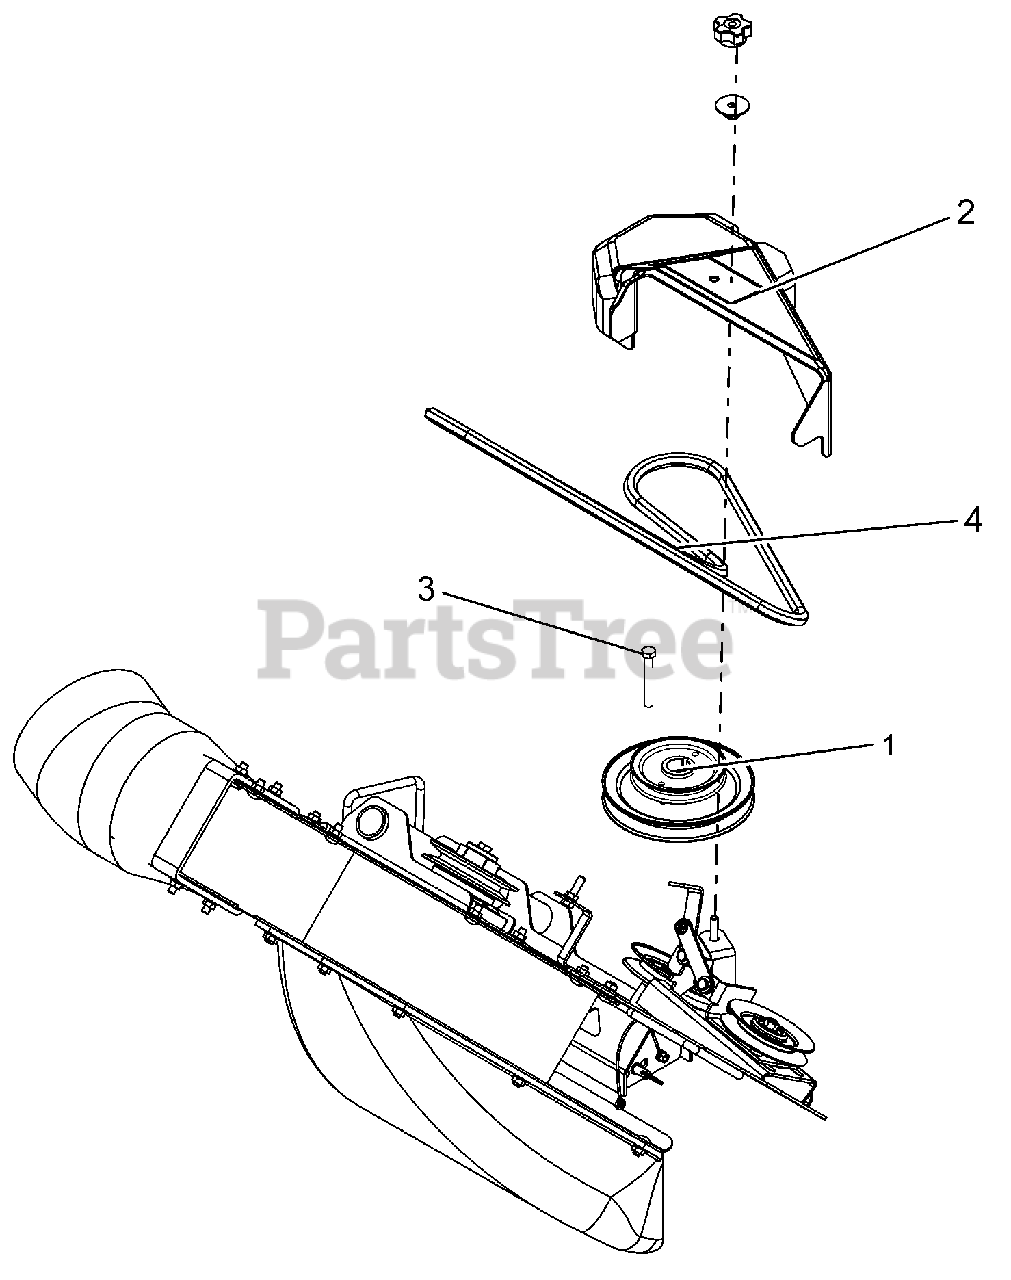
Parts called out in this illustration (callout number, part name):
1	PULLEY, DOUBLE 1.000 ID X 6.750 & 4.250 OD (BLACK)
2	COVER, BELT 52 BLOWER
3	BLT-HEX .38-16X2.75 GR8 YWZC
4	HEX BELT, AA-WRAPPED
